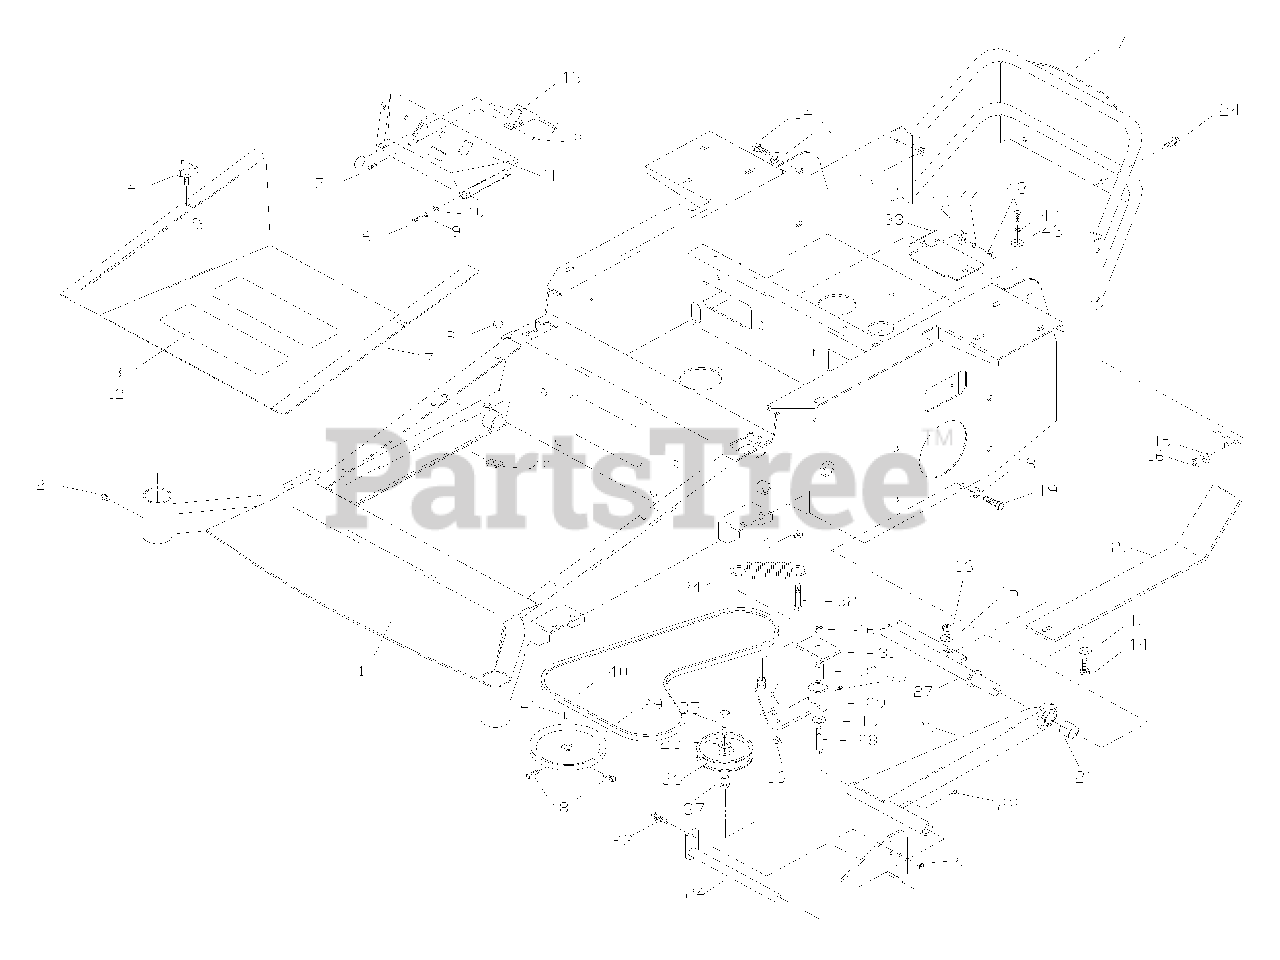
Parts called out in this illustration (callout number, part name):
1	FRAME 72" MODEL
1	FRAME 52" & 61
3	ANTI SKID PAD
4	KNOB
5	HCS # 10 X 1/2
6	1/4 x 5/8 SELF TAP
7	FOOT PLATE
9	1/4 LOCK WASHER
10	1/4 FLAT WASHER
11	CONSOLE W DECAL
12	NUT #10 NYLOC
13	THROTTLE CABLE
14	HCS 3/8 X 1.0
15	3/8 FLAT WASHER
16	NUT 3/8 LOCK
17	ENGINE GUARD
18	7/16 LOCK WASHER
19	HCS 7/16 X 1.0 GD 8
20	SKID PLATE
21	STRUT SPACER
22	ZERK
23	HCS 5/16 X 3/4
24	STRUT PIN
25	NUT 5/16 LOCK
26	STRUT
27	CROSS SHAFT 72"
27	CROSS SHAFT 52" & 61"
28	HCS 1/2 X 3.25
29	IDLER ARM
30	PIVOT BUSHING
31	SUPPORT PLATE
32	HCS 3/8 X 1.5
33	IDLER COVER
35	HCS 3/8 X 1.75
36	IDLER PULLEY
37	IDLER BUSHING
38	5/16 X 5/8 SETSCW.
40	PUMP BELT
41	KEY 5mm SQ.
43	5/16 FLAT WASHER
44	5/16 LOCK WASHER
48	HCS 5/16 X 1.0
